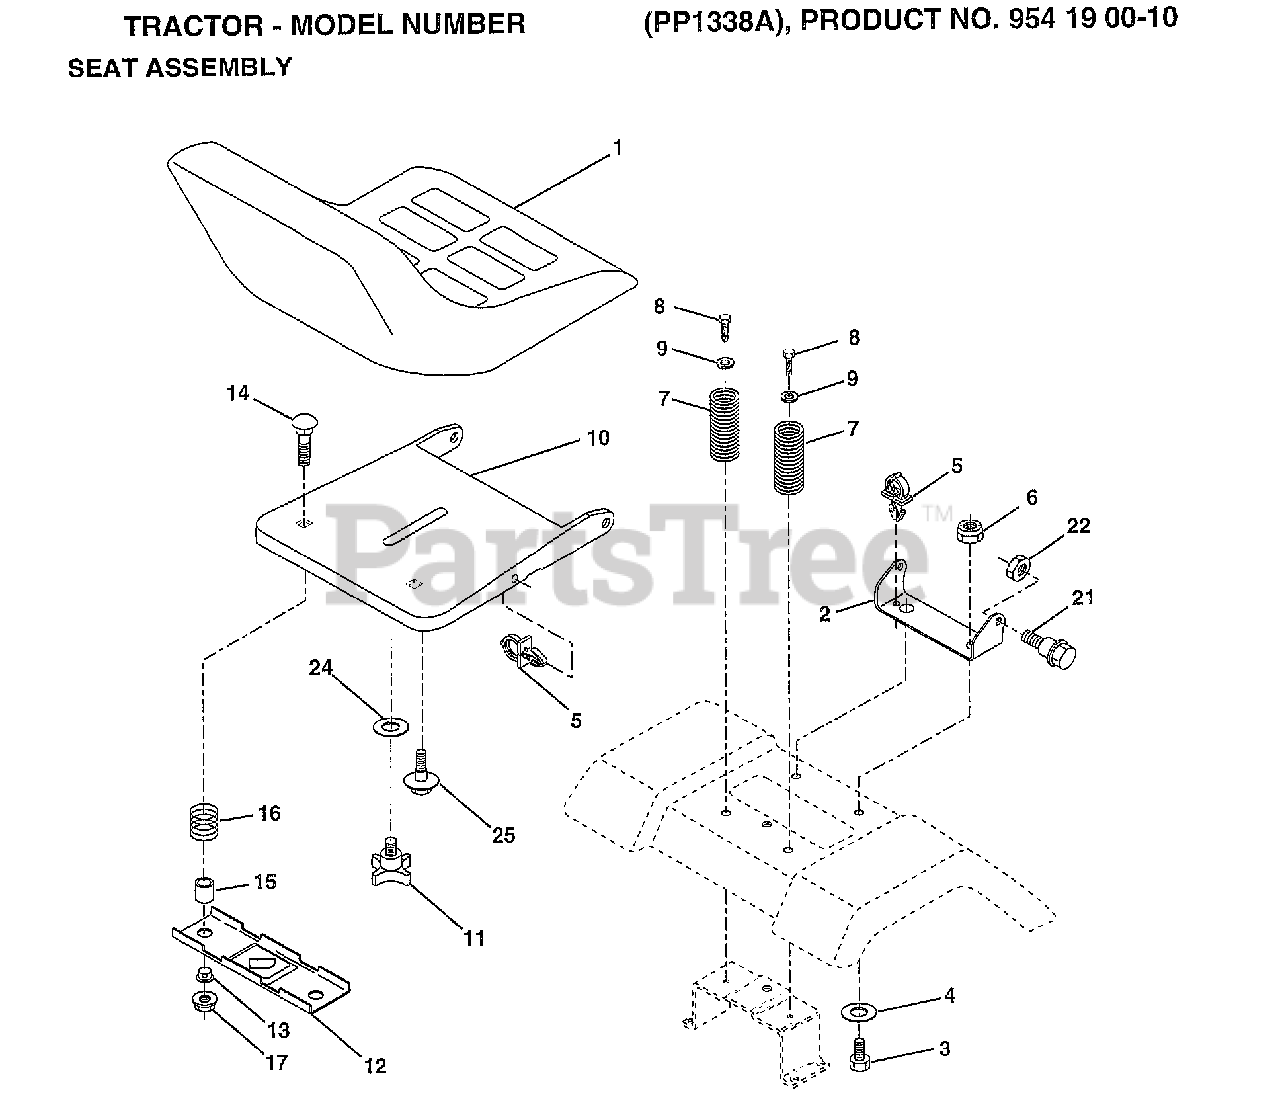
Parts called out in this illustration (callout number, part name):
1	SEAT
2	BRACKET PVT SEAT
3	BOLT
4	WASHER PM
5	CLIP.PUSH-IN.HING
6	NUT
7	SPRING COMPRESSIO
8	SCREW GTV
9	WASHER
10	PAN-SEAT
11	"KNOB 1/2"" YT"
12	BRKT SWITCH
13	BUSHING
15	SPLIT SPACER
16	SPRING
21	"BOLT,SHOULDER"
22	NUT
23	BOLT
24	WASHER
25	"BOLT,SHOULDER"
